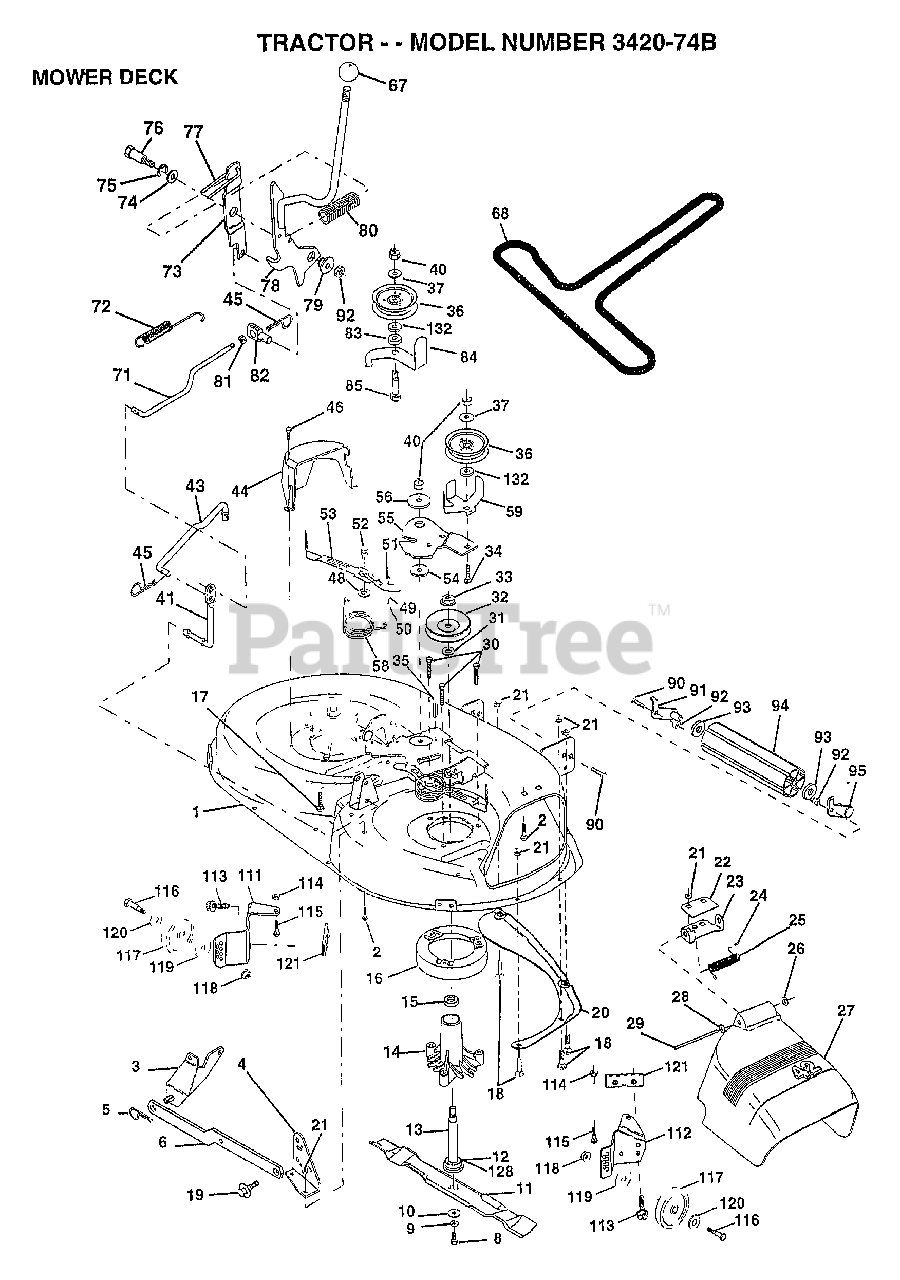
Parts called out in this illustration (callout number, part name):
1	DECK.WELD.42.
2	BOLT
3	BRKT ASM SWAY BAR
4	BRKT DECK SW BAR
8	BLADE BOLT
10	WASHER.HARD.BLADE
11	"BLADE.42"" MULCHER"
12	BEARING.BALL
14	HSG ASM MANDREL
15	BEARING
16	STRIPPER RND MWR
17	BOLT RDHD 3/8-16
18	BOLT
19	BOLT SHD 5/16-18
22	STIFFENER BRKT
23	DEFLECTOR BRKT
24	CAP-SLEEVE LT
25	SPRING TORSION
26	NUT PUSH M
27	DEFLECTOR.SHIELD
28	WASHER
29	HINGE ROD
31	WASHER
34	BOLT
35	XMAS TREE FASTNER
36	FLAT IDLER PULLEY
37	WASHER
41	PIVOT ROD
43	ROD CLUTCH W/NIBS
44	GUARD MAND LH BLK
45	RETAINER M
46	SCREW.1/4-20X5/8
48	HARD SMALL WASHER
50	SHOULDER BOLT
51	LOCKNUT
52	BOLT.SHLD.5/16-18
54	HARDENED WASHER
56	SPACER RETAINER
58	SPRING TORSN BRAK
59	GUARD IDLER TUV
68	BELT.V.T-PATH
71	ROD CLUTCH 38/42
72	RETURN SPRING
73	CLUTCH ARM SECOND
74	WASHER
75	RING
76	SHOULDER BOLT
77	SPRING KEEPER
78	LOWER ASM CLUTCH PRIMARY YP
79	BUSHING
80	SPRING.CLUTCH.MWR
81	NUT
82	TRUNION ADJ
83	WASHER
84	"KEEPER-BELT,FIXED"
85	BOLT RDHD 3/8-16
90	BOLT
92	NUT
93	WASHER
111	BRACKET.GWHL.LH.
112	BRACKET.GWHL.RH.
113	SCREW
116	BOLT M
117	WHEEL.GAGE.BLK.PL
118	LOCKNUT
119	WASHER
120	WASHER
121	BRACKET.EXTRD.GWL
128	WASHER.FELT.
132	WASHER GT
